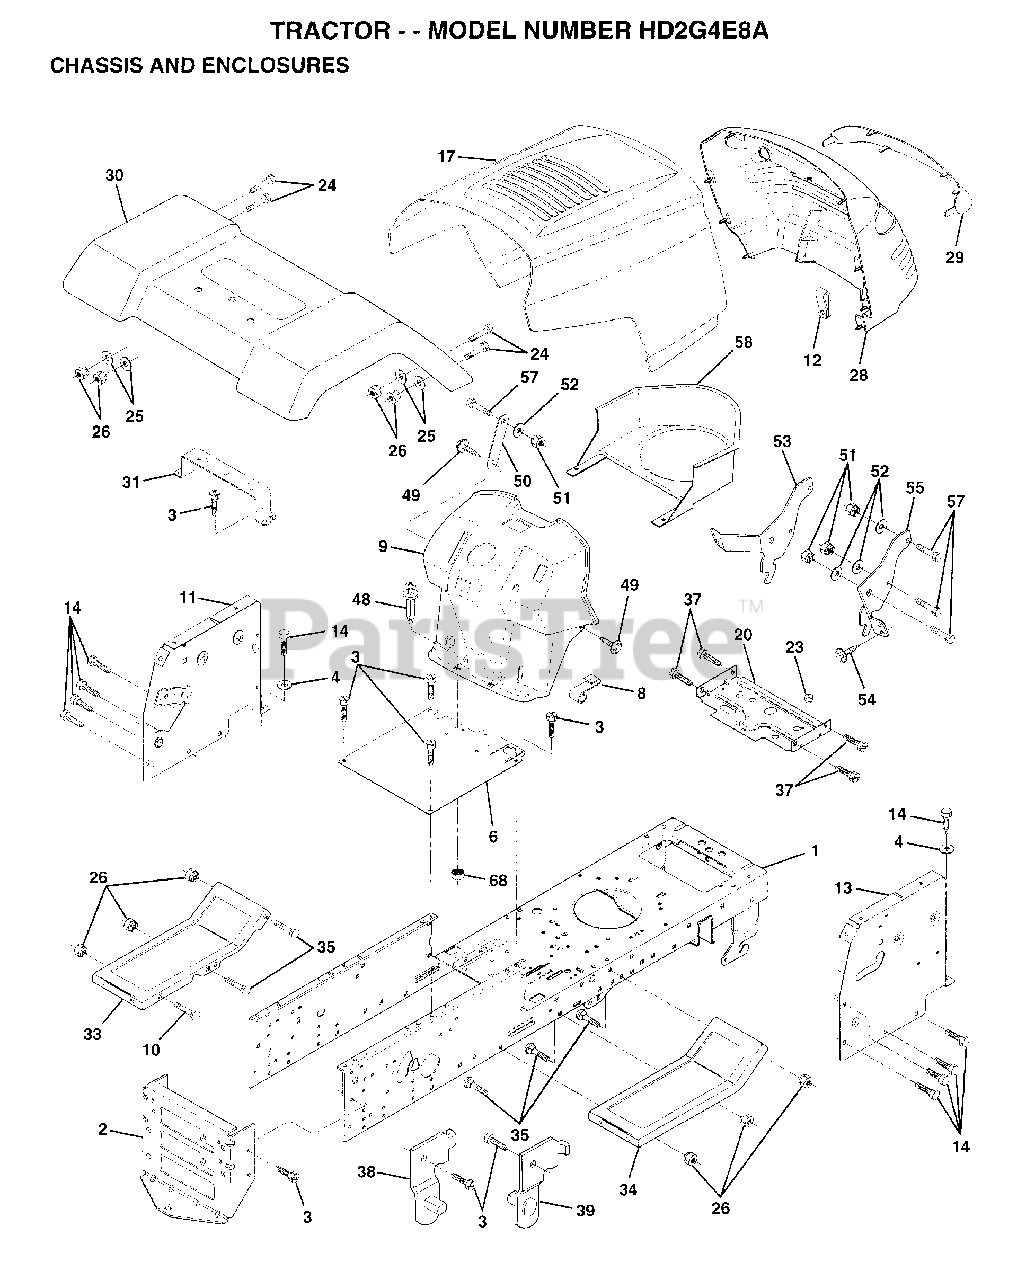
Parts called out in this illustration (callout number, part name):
1	CHASSIS.WLD.11GA
3	SCREW
4	WASHER
8	"CLIP,INSULATOR"
11	PANEL.DASH.LH.
12	CLIP.TINNERMAN
13	PANEL.DASH.RH
14	SCREW LT
20	PLATE.MTG.BTRY.TK
24	BOLT
25	WASHER
26	NUT
29	LENS GRILLE
31	BRKT FENDER
33	FOOTREST.LH.PERF.
34	FOOTREST.RH.PERF.
35	BOLT
37	SCREW LT
38	BRACKET ASM LH
39	BRACKET ASM RH
48	RIVET.PUSH.PLATE
49	SCREW HEX CRT
50	BRACE SUPT DASH
51	NUT
52	WASHER
53	BRACKET.GRILLE.LH
55	BRACKET.GRILLE.RH
56	BOLT
58	AIR DUCT
68	NUT
